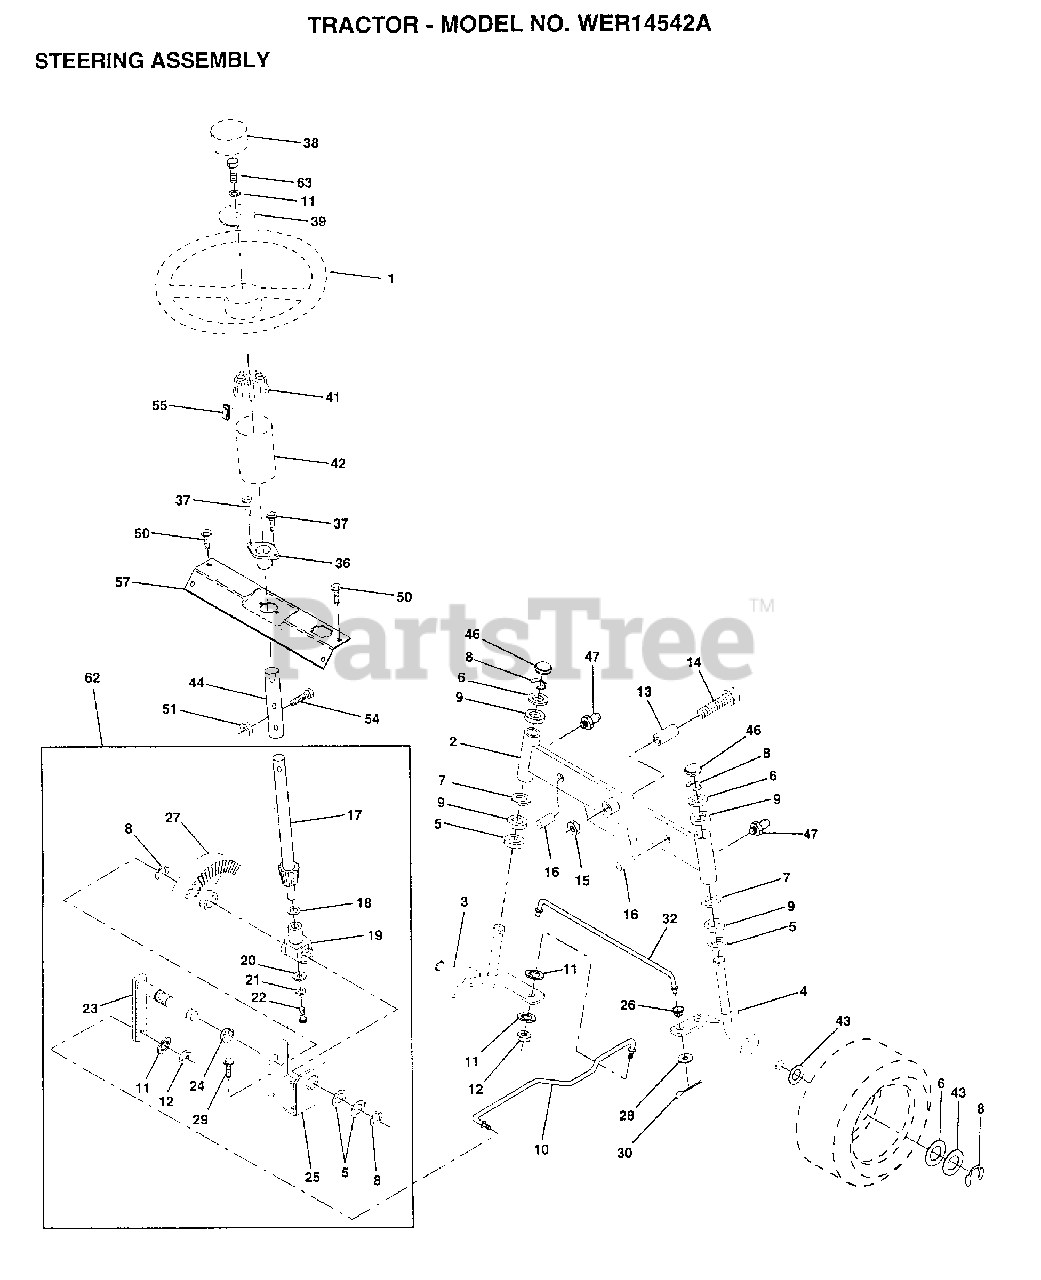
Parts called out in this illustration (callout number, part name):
2	AXLE ASM FRONT
3	SPINDLE LH
4	SPINDLE RH
5	WASHER .T
6	WASHER
7	WASHER
8	RING
9	COL. SRTG. BEAR.
11	LOCKWASHER
13	BEARING
14	BOLT HEX 5/8-11
15	"NUT-LOC,FLANGE LT"
16	AXLE PIN
17	SHAFT ASM STEERIN
18	THRUST WASHER
19	SUPPORT.SHAFT
21	LOCKWASHER
22	SCREW.SCKTHD.CAP
24	NYLINER T
25	"BRKT,STEERING"
26	BUSHING.DRAGLINK
27	GEAR SECTOR
28	WASHER
29	SCREW
30	COTTER PIN
32	TIE ROD
37	"SCREW-TT,10-32 FL"
38	ST WHL INSERT CAP
39	WASHER T
41	ADAPTER LT
42	BOOT SHAFT STEER
43	WASHER
44	SHAFT EXT STEERIN
46	CAP
47	ZERK M
50	SCREW HEX CRT
51	NUT
54	BOLT
55	CLIP TINNERMAN
57	SUPPORT SHAFT STR
63	BOLT
